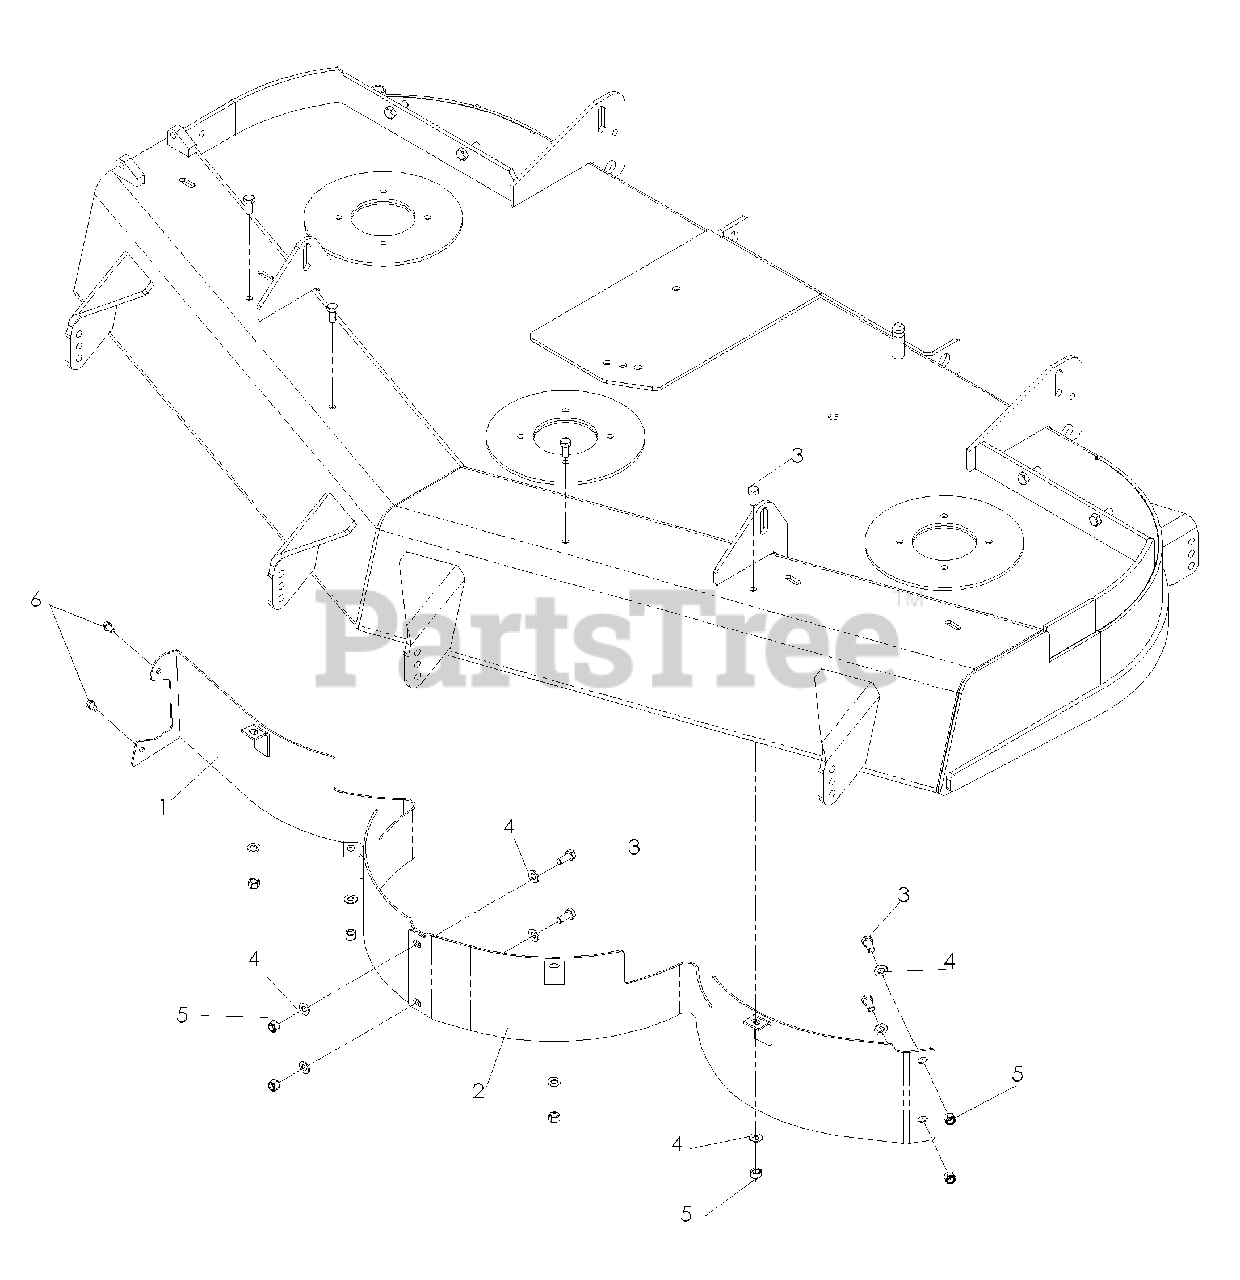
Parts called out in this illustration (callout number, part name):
1	BAFFLE, FRONT, RT
2	BAFFLE, FRONT, LT
3	HCS 5/16-18 x 3/4
4	WASHER 5/16 FLAT SAE
5	NUT 5/16-18 HEX NYLOC
6	SCREW 1/4-20, SLF TAP
